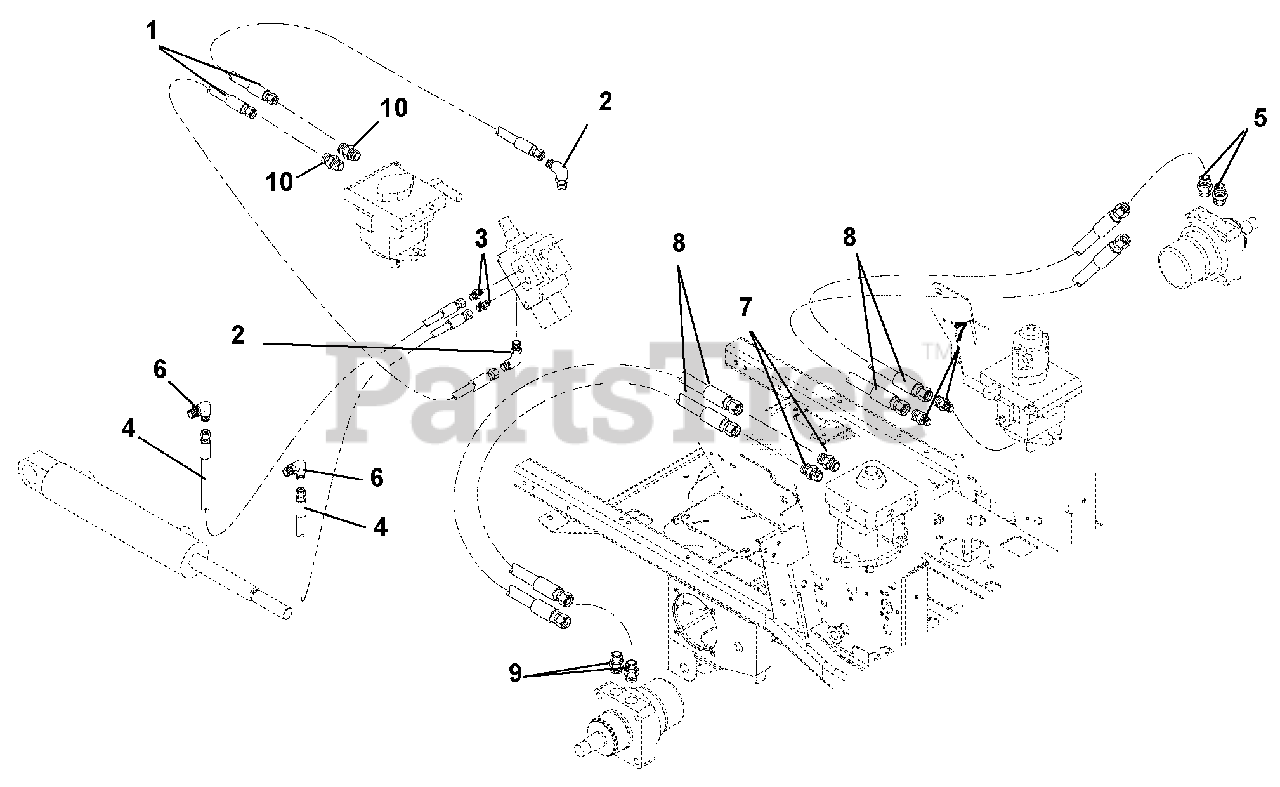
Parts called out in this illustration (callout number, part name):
1	Hose, Hydraulic
2	Hydraulic, Fitting Elbow
3	Adapter (4 – 6F5OLO)
4	Hose, Hydraulic
5	Fitting, Hydraulic Straight (8 – 10 F5OLO – S)
6	Fitting, Hydraulic (4 C5OLO)
7	Adapter, Face Seal 8 x 8 .50 O-Ring
8	Hose, Hydraulic .50
9	Adapter, Hydraulic Steel (M10 O – M8F)
10	Fitting, Hydraulic (4 F5OLO) (Supplied with pump)
